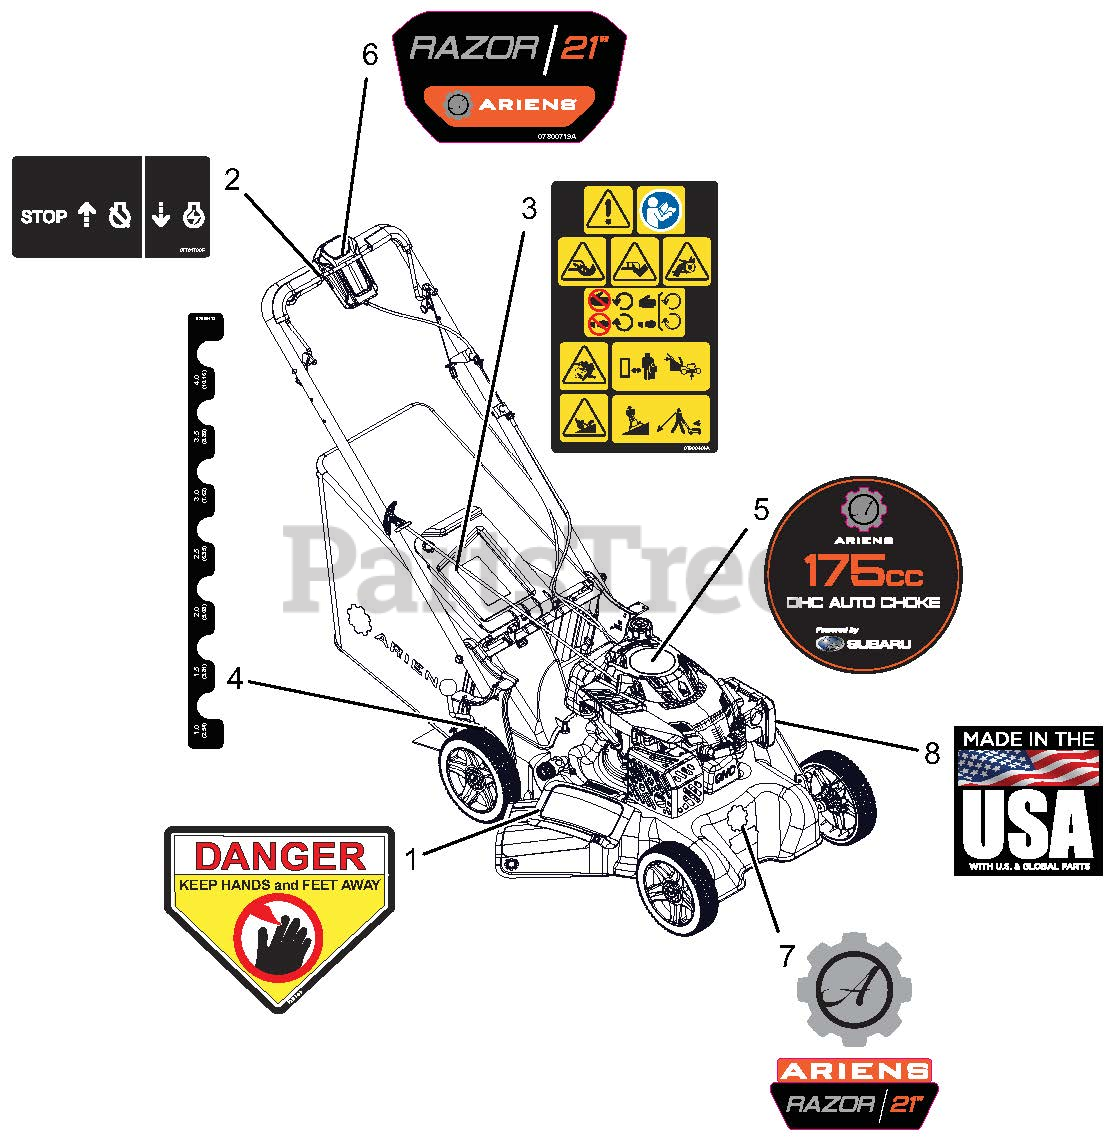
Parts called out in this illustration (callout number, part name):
1	DECAL, DANGER
2	DECAL - ENGINE CONTROL
3	DECAL,MAIN SAFETY_WAW LM
4	DECAL, HOC
5	DECAL-ENGINE STYLE-RAZOR
6	DECAL-CONTROL-RAZOR
7	DECAL-ARIENS RAZOR 21"
8	DECAL, MADE IN USA
